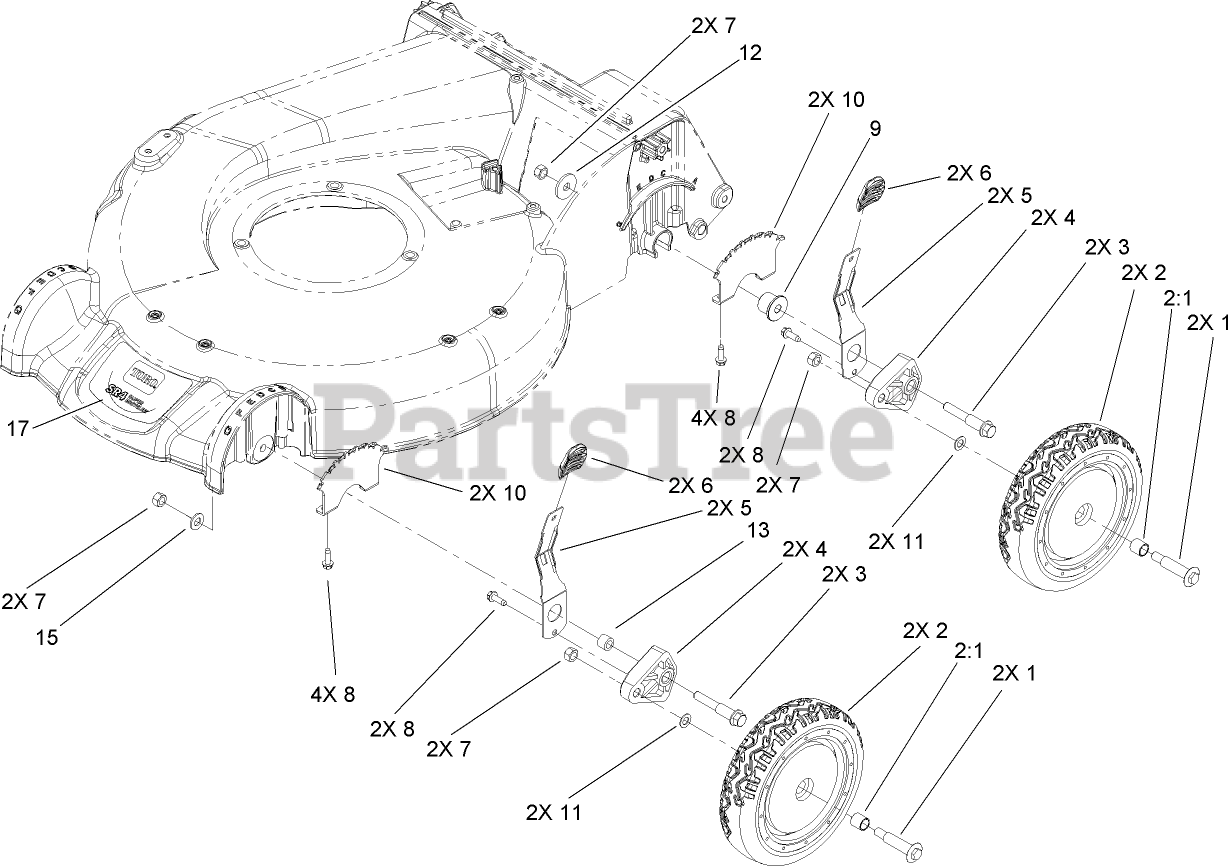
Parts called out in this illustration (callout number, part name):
1	BOLT-SHOULDER
2	WHEEL ASM
2:1	BUSHING
4	ARM-PIVOT
5	ARM-SPRING
6	KNOB-LEVER, HOC
7	LOCKNUT
8	SCREW-HWHTF
9	SPACER-HP
10	PLATE-HOC
11	WASHER
12	WASHER
13	SPACER-WHEEL
15	WASHER-FLAT
17	DECAL-SUPERCARE
